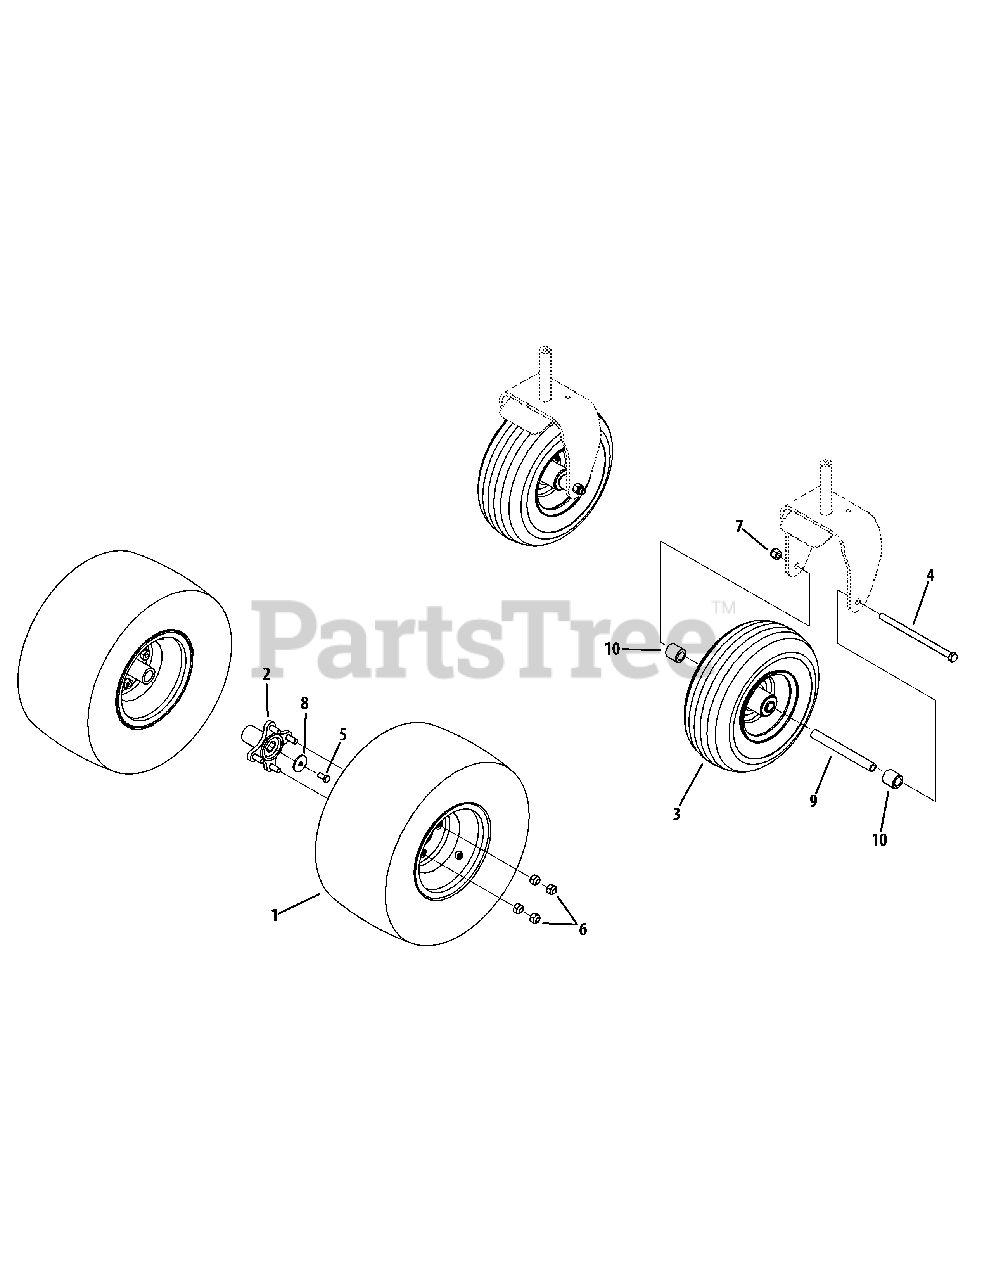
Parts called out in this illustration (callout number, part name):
1	Wheel Assy., 18 x 9.5-8 (48" Decks)
1	Wheel Assy., 20 x 10.00 x 8 (54" & 60" Decks)
2	Wheel Hub Assembly
4	Hex Screw, 1/2-20 x 7.25
5	Hex Screw, 3/8-16 x .750 (48" Only)
6	Lug Nut, 7/16-14
7	Hex Lock Nut, 1/2-20
8	Flat Washer, .390 x 1.500 x .134 (48" Only)
9	Spacer, .51 x .75 x 1.25
10	Spacer, .76 x 1.23 x 1.57
